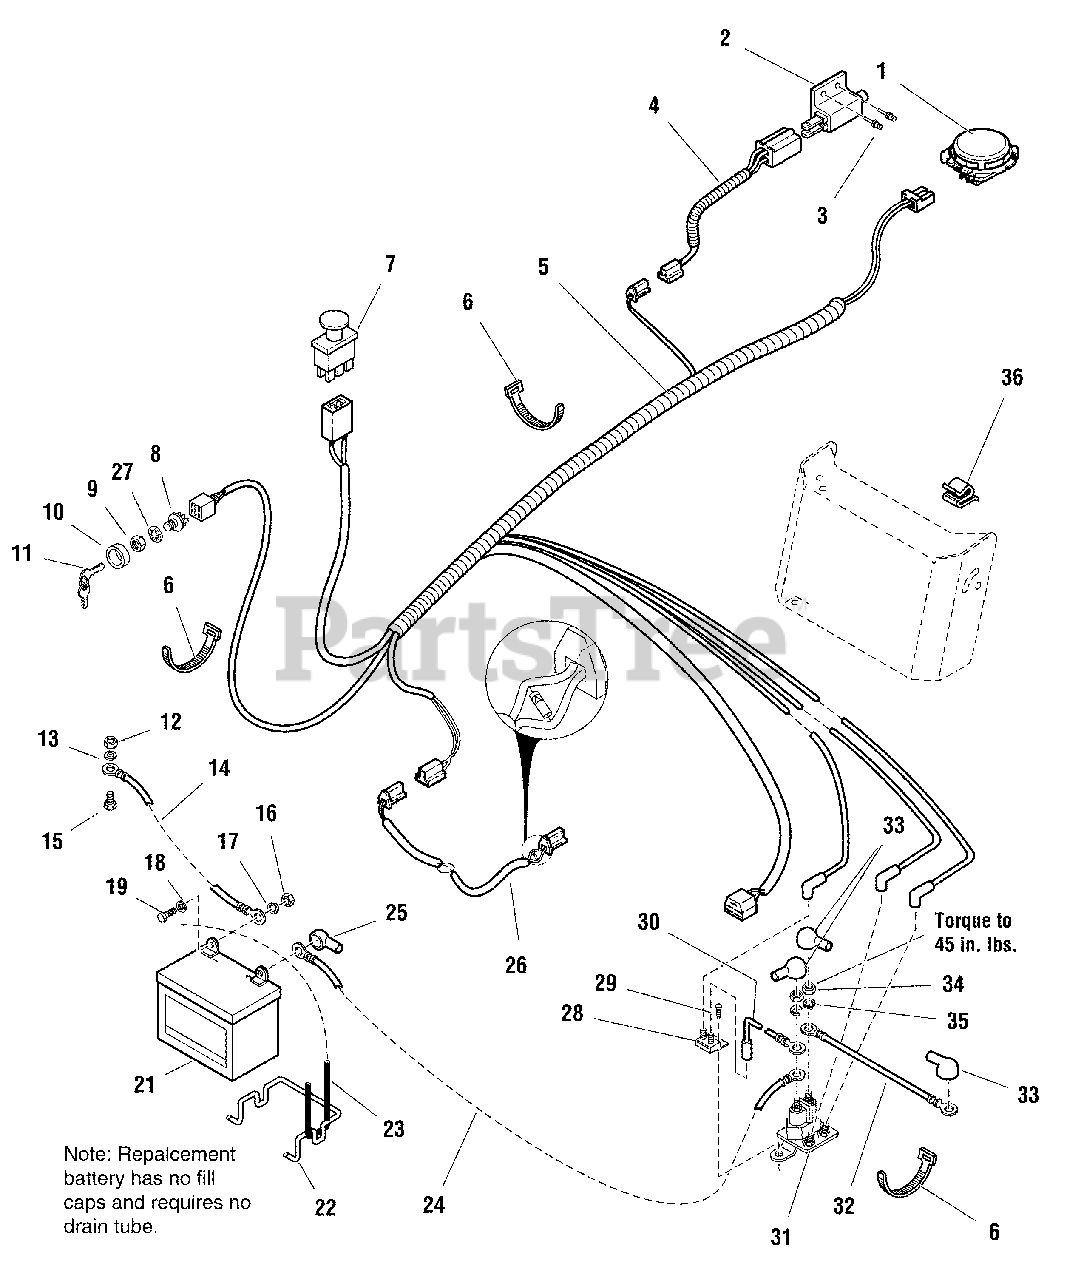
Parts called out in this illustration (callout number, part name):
1	SWITCH, Seat
2	SWITCH, Neutral Start
4	WIRE ASSEMBLY, Ground
5	HARNESS, Wiring
6	TIE, Self-Locking
7	SWITCH, PTO, Electric Clutch
8	SWITCH, Ignition (6 pole), (Includes Ref. Nos. 9, 10, 11 & 27)
9	NUT, Hex
10	COVER, Keyswitch
11	KEYS (Set of 2 Keys)
12	NUT, Hex Flange Whiz Lock, 3/8-16
13	WASHER, Lock, External Tooth, 3/8
14	CABLE, Battery Ground
15	CAPSCREW, Hex Head, 3/8-16 x 5/8
16	NUT, Hex, 1/4-20
17	WASHER, Lock, 1/4
18	WASHER
19	CAPSCREW, Hex Head, 1/4-20 x 3/4
22	BRACE, Battery
23	STRAP, Battery
24	CABLE, Battery to Solenoid
25	BOOT, Insulator
26	WIRE ASSEMBLY, Clutch
27	WASHER, Internal Tooth, 5/8
28	CIRCUIT BREAKER
29	CAPSCREW, Hex Washer Head, Taptite, 1/4-20 x 1/2
30	WIRE ASSEMBLY
31	SOLENOID
32	CABLE, Solenoid to Starter
33	COVER, Terminal
34	NUT, Hex, 5/16-24
35	WASHER, Lock, 5/16
